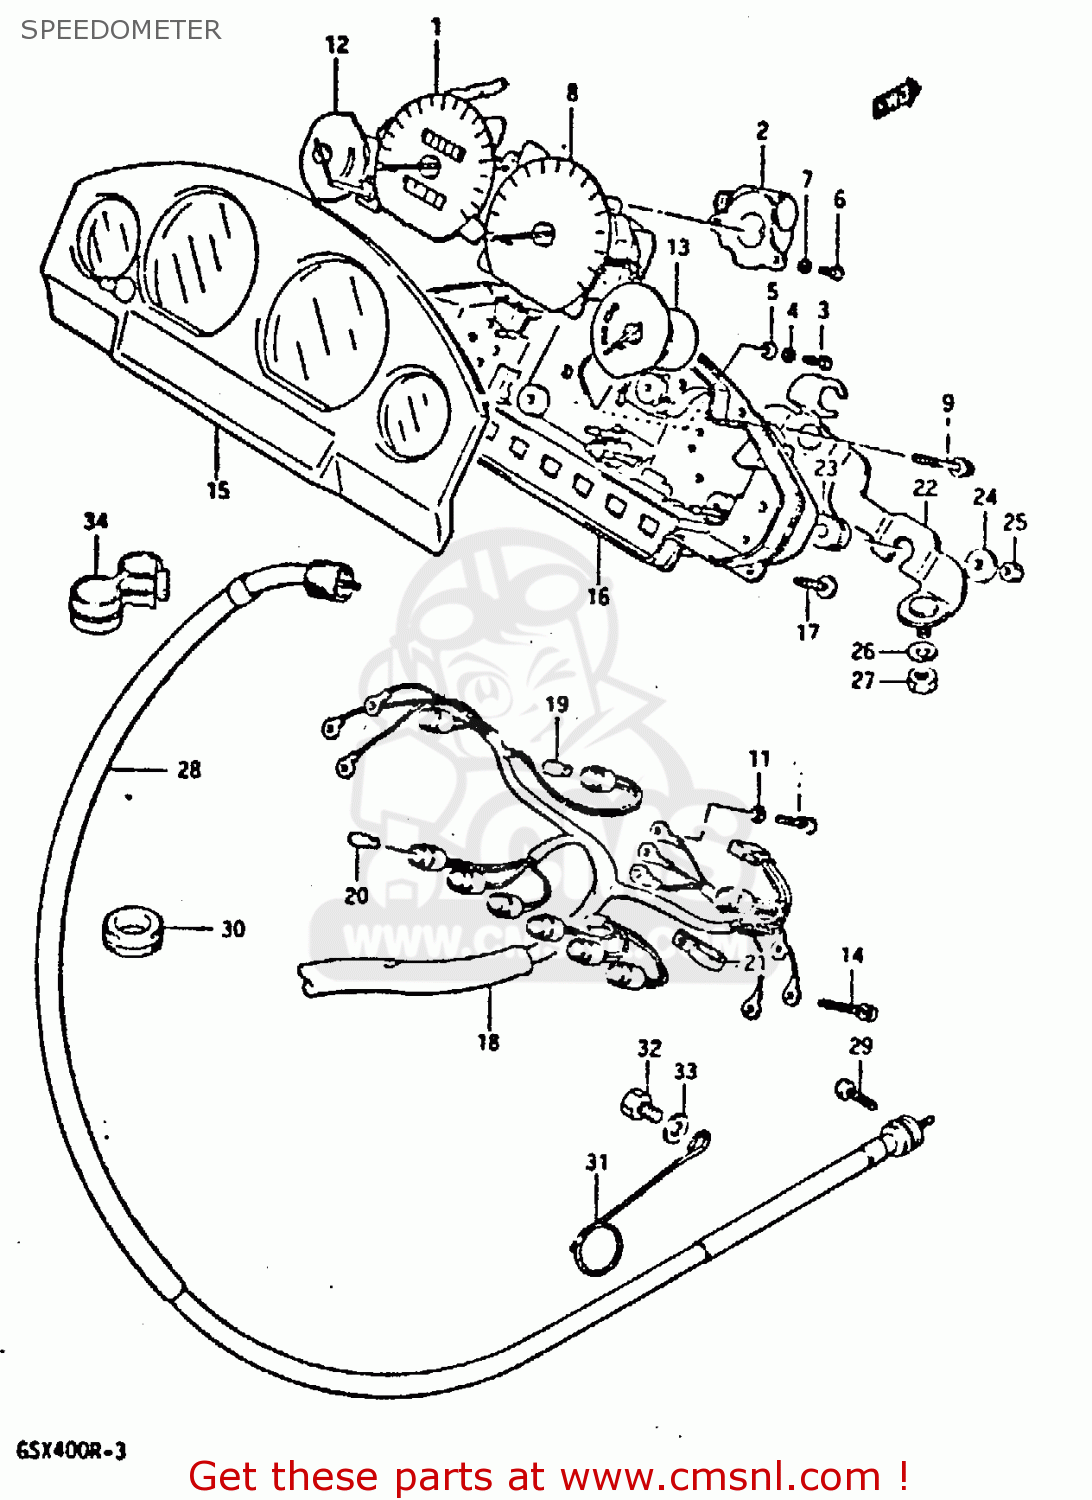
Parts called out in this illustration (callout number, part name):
1	SPEEDOM GSX 400
2	GEAR BOX,SPEEDOMETER
3	SCREWM4X0.7X10
4	LOCK WASHER
5	WASHER
6	SCREW
7	LOCK WASHER
8	TACHOM GSX 400
9	SCREW (4X36)
10	SCREW
11	LOCK WASHER
12	FUEL METER
13	TEMPERATURE MET
14	SCREW(3X22)
15	METER HOOD
16	METER CASE
17	SCREW
19	BULB 12V 45/45W BF130-0
20	BULB(12V1.7W,T6.5)
21	CLAMP
22	METER BRACKET
23	CUSHION
24	WASHER (5.5X16X1.2)
25	NUT
26	WASHER,LOCK
27	NUT
28	CABLE ASSY,SPEEDOMETER
29	SCREW
30	GROMMET
31	CLAMP,SPEEDOMETER CABLE
32	BOLT
33	WASHER
34	GUIDE,SPEEDOMETER CABLE
